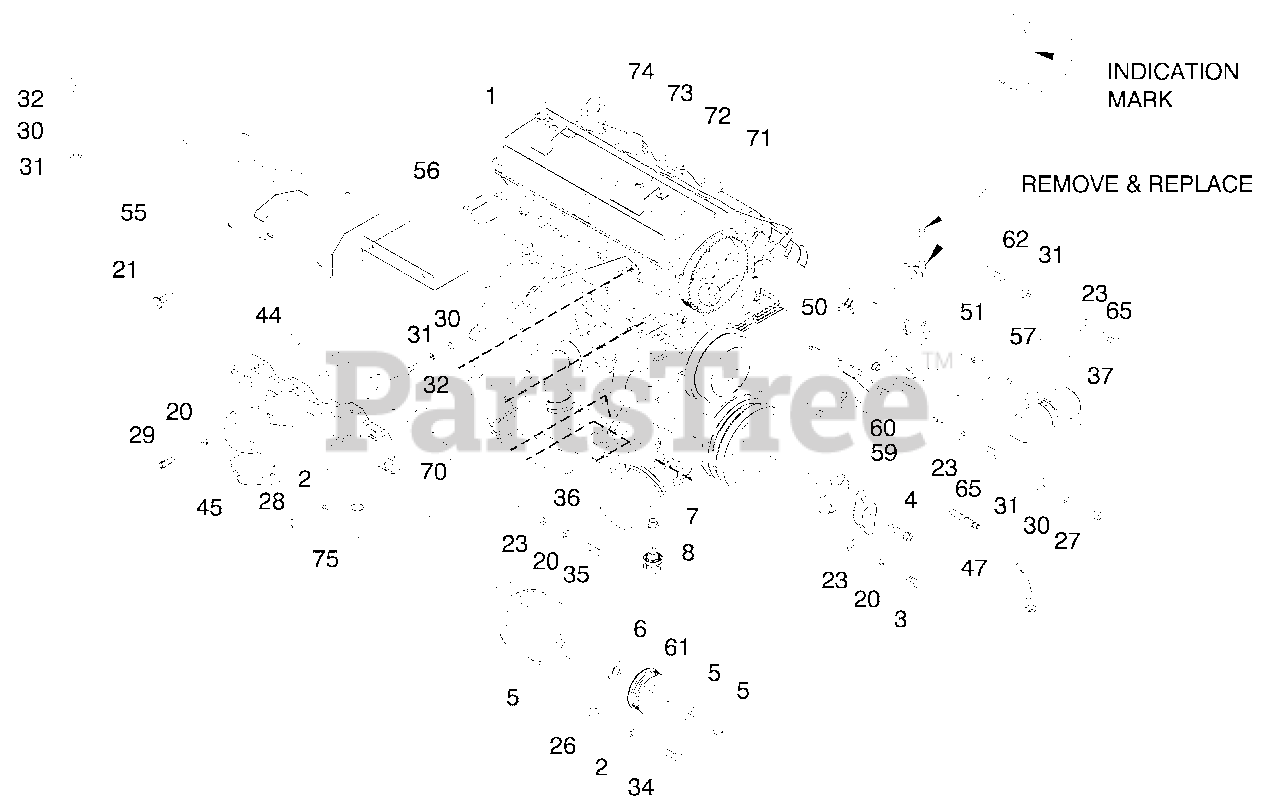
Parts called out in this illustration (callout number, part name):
1	ENGINE 2.4LG2 4G64 CERT
2	WASHER LOCK M10
3	SCREW HHC M8-1.25X 35 G8.8
4	SCREW SHC M14-1.5 X 35 G10.9
5	ALTERNATOR DC W/O UT P ULLEY
6	SPACER DC ALTERNATOR P ULLEY
7	ADAPTOR 1/8 NPTF TO 1/8 BSPT
8	SWITCH OIL PRESS URE 10 PSI 2 POL (R-PANEL)
20	WASHER LOCK M8-5/16
21	SCREW THF M6-1 X 16 N WA Z/JS
23	WASHER FLAT 5/16-M8ZINC
26	WASHER FLAT 3/8-M10ZINC
27	NUT HEX M 6 X 1 .0G 8 Y E LC H R
28	N UT HEX M10-1.25 G 8Y E L CHR
29	SCREW SHC M8-1.25X 25G12.9
30	WASHER LOCK M6-1/4
31	WASHER FLAT 1/4-M6 ZINC
32	SCREW HHC M6-1.0X 12 G8.8
34	SCREW HHC M10-1.5X60G8.8
35	SCREW HHC M8-1.25 X 25 G10.9
36	OIL FILTER G2 ENGINE
37	COIL PACK
44	GASKET EXHAUST MANIFOLD
45	EXHAU ST MANIFOLD G2 (MACHINE) (25KW, 35KW & 45KW)
47	ASSY MAGPICK UP(3/8-24 MALE)
50	CAM SENSOR PIN ASSY
51	COVER CAM GEAR G2 REWORKED
55	SHIELD HEAT G2
56	SHIELD HEAT SML
57	BRACKET COIL PACK
59	ADAPTER 2.4L CRANKSHAFT MACH
60	POLY V-BELT G2 (3600 RPM)
61	P ULLEY DC ALTERNATOR (3600 RPM)
62	SCREW HHC M6-1.0 X 35 G8.8 BLK
65	SCREW HHC M8-1.25X70G8.8
70	O-RING SIZE 9.0MM X 2.0MM NITR
71	CABLE, SPARK PLU G, NO.1
72	CABLE, SPARK PLU G, NO.2
73	CABLE, SPARK PLU G, NO.3
74	CABLE, SPARK PLU G, NO.4
75	PLUG TAPER
